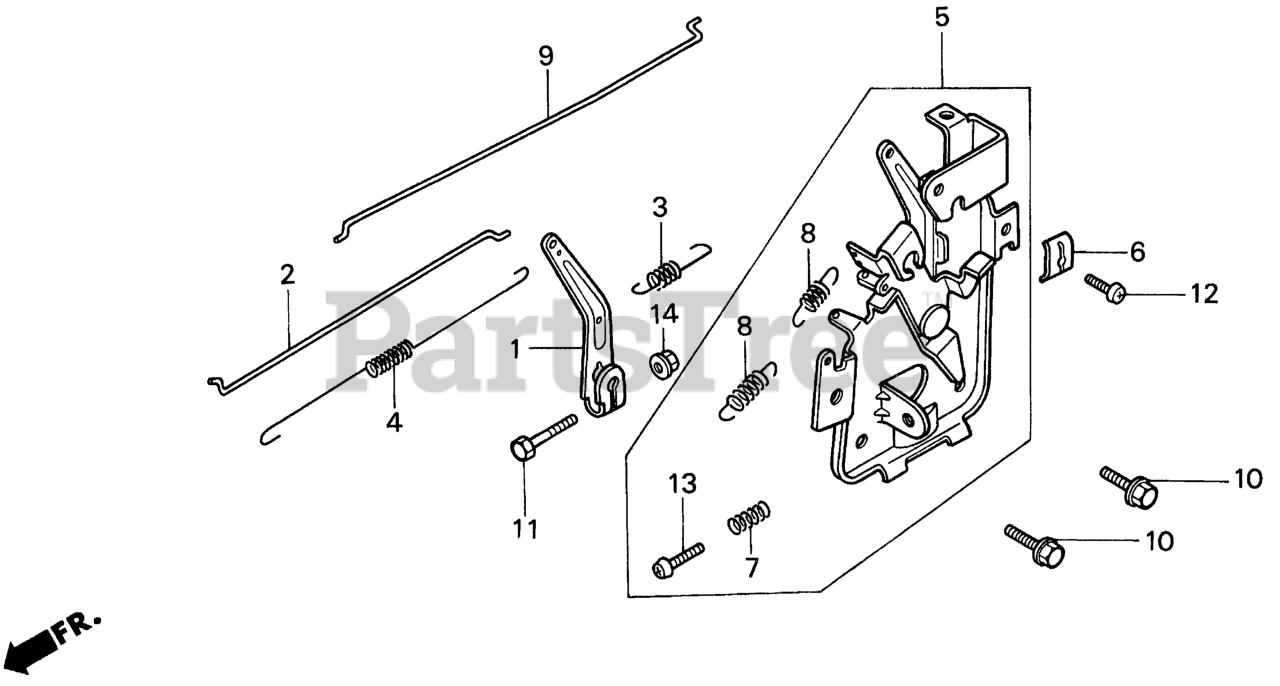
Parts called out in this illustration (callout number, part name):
1	ARM, GOVERNOR
2	ROD, GOVERNOR
3	SPRING, GOVERNOR
4	SPRING, THROTTLE RETURN
5	CONTROL ASSY.
6	HOLDER, CABLE
7	SPRING, CONTROL ADJUSTING Use from Engine SN 2327377.
8	SPRING, CABLE RETURN
9	ROD, CHOKE
10	BOLT, FLANGE (6X12) (CT200)
11	BOLT, GOVERNOR ARM
12	SCREW, PAN (5X16)
13	SCREW, PAN (5X20)
14	NUT, FLANGE (6MM)
